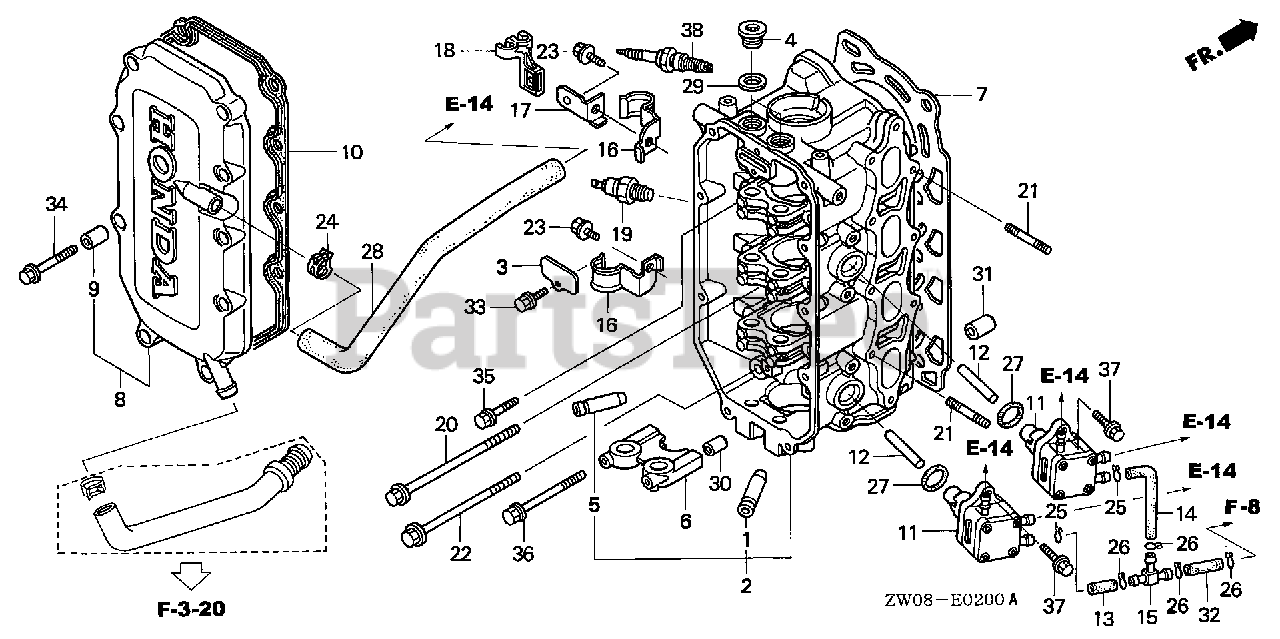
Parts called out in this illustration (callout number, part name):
1	GUIDE, VALVE (OVER SIZE)
2	CYLINDER HEAD *NH8* (DARK GRAY)
3	PLATE, OIL CHAMBER
4	BOLT, SEALING (20MM)
5	GUIDE, IN VALVE
6	HOLDER, CAM THRUST
7	GASKET, CYLINDER HEAD
8	COVER, CYLINDER HEAD
9	COLLAR, HEAD COVER
10	GASKET, HEAD COVER
11	PUMP ASSY., FUEL
12	LIFTER, FUEL PUMP
13	TUBE B, FUEL
14	TUBE C, FUEL
16	CLAMP, HOSE
17	STAY A, IGNITION WIRE CLAMP
18	CLAMP A, IGNITION WIRE
19	SWITCH ASSY., THERMOSTAT
20	BOLT-WASHER (10X140) (SAGA)
21	BOLT, STUD (8X22)
22	BOLT-WASHER (10X120.5) (SAGA)
23	BOLT, FLANGE (6X12) (CT200)
24	CLAMP, TUBE (D21)
25	CLIP, TUBE (B10)
26	CLIP, TUBE (B12)
27	O-RING (20.8X2.4)
28	TUBE, BREATHER
29	WASHER, DRAIN PLUG (20MM)
30	PIN A, DOWEL (8X14)
31	PIN A, DOWEL (12X16)
32	BULK HOSE, FUEL (7.5X8000) (7.3X160)
33	BOLT, FLANGE (6X12) Use up to Engine SN 1543277.
34	BOLT, FLANGE (6X35)
35	BOLT, FLANGE (8X40)
36	BOLT, FLANGE (6X80)
37	BOLT, FLANGE (6X20) (SH)
38	SPARK PLUG (DR7EA) (NGK)
38	SPARK PLUG (X22ESR-U) (DENSO)
